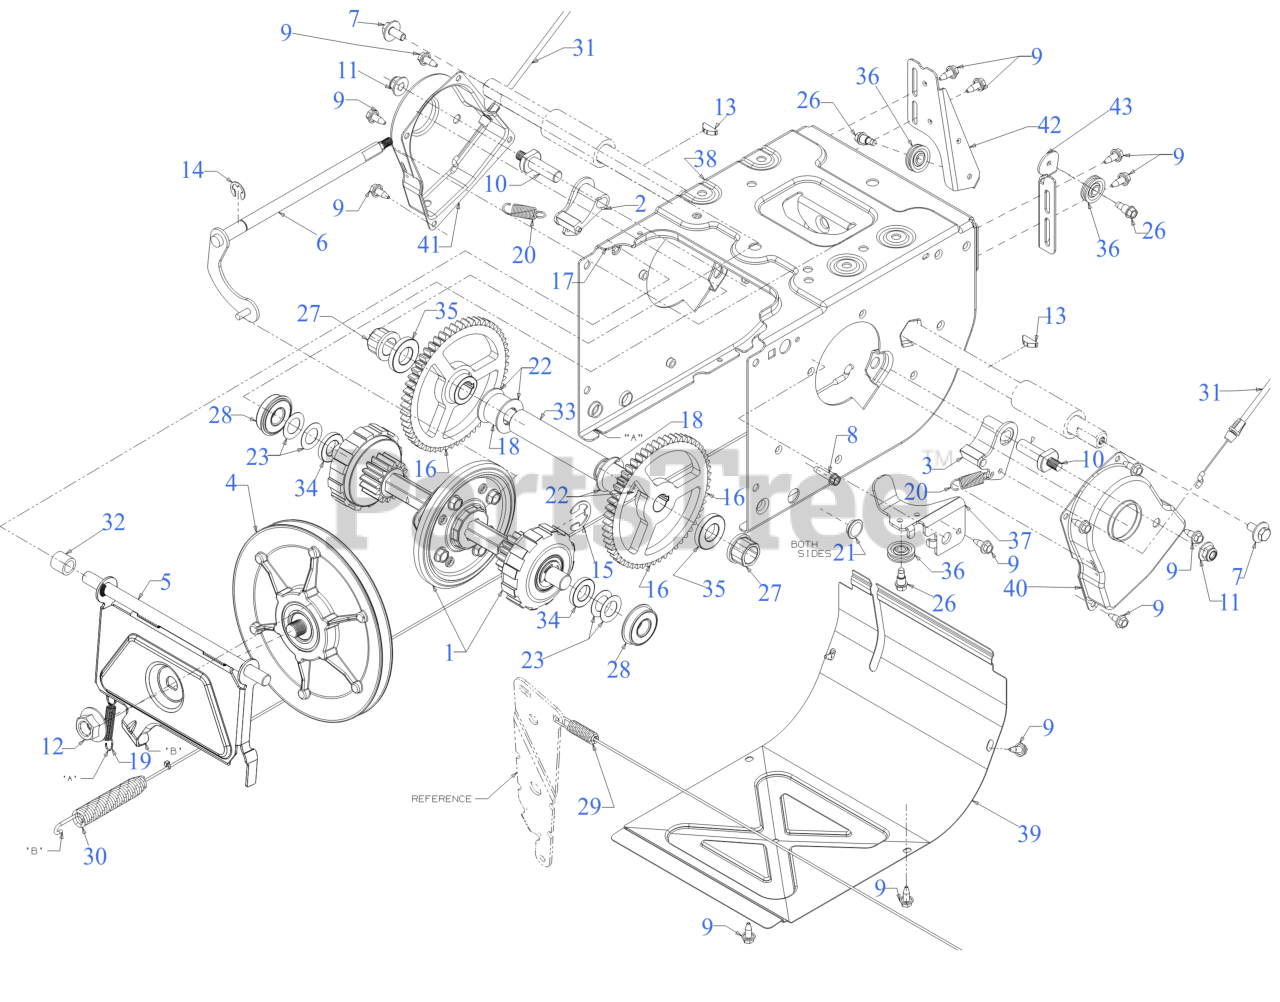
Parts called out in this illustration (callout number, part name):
1	PLANETARY FRICTION WHEEL HEX SHAFT
2	DOGG ASSEMBLY (RH)
3	DOGG ASSEMBLY (LH)
4	FRICTION WHEEL DISC ASSEMBLY
5	FRICTION WHEEL BRACKET (POWDER BLACK)
6	SHIFT ROD ASSEMBLY
7	SCREW 5/16-24 x .750 GR5
8	SCREW 1/4-20 x 1.00
9	SCREW 1/4-20X.625
10	ACTUATOR SHAFT
12	FLANGE NUT 5/8-18
13	KEY 3/16 x 3/4
14	E-RING FOR .500 SHAFT
15	RETAINING RING
18	SPACER: .76ID x .75
19	EXTENSION SPRING
20	EXTENSION SPRING
22	FLAT WASHER .760ID X1.49OD x .06
22	FLAT WASHER
23	FLAT WASHER .67X 1.174X .02
26	SHOULDER SCREW
27	FLANGE BEARING
28	BALL BEARING W/RET
29	AUGER DRIVE CABLE 47.48"
30	WHEEL DRIVE CABLE 44.955"
30	EXTENSION SPRING .55 x 6.25
31	STEERING CABLE
32	SPACER-.513 ID x .703 OD x .69
33	AXLE SUPPORT TUBE
35	AXLE SPACER
36	CABLE GUIDE ROLLER
37	AUGER CABLE BRACKET
38	DRIVE FRAME
42	CABLE GUIDE BRACKET (DRIVE)
43	CABLE GUIDE BRACKET (AUGER)
